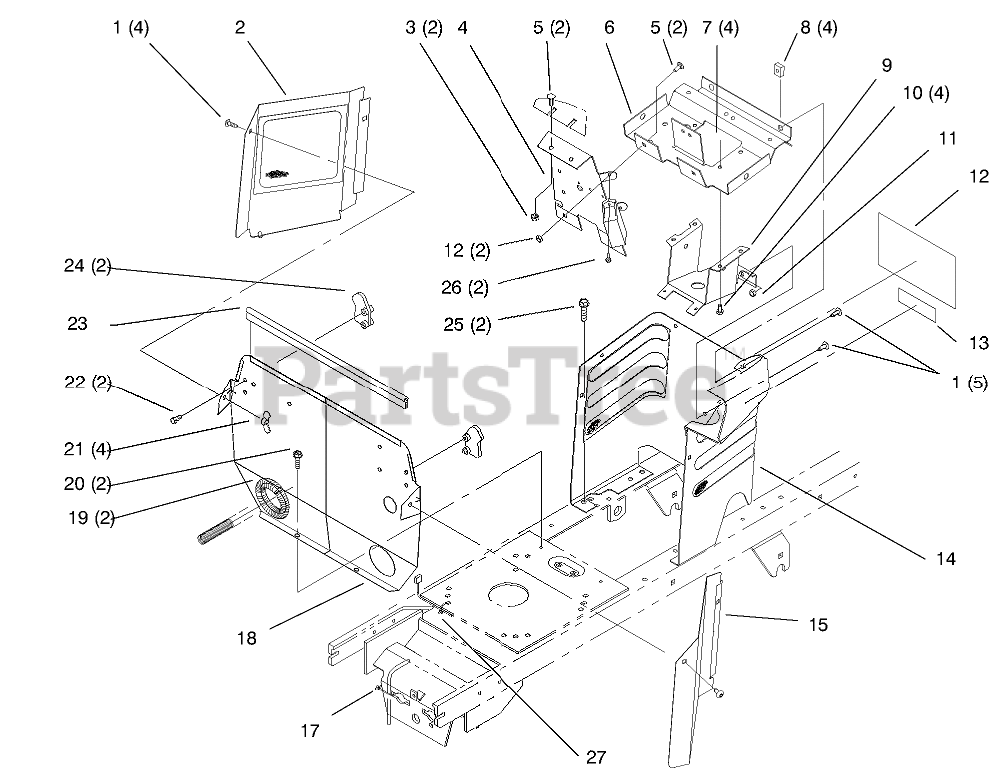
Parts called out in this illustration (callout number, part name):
1	SCREW-HH
2	RH SIDE COVER ASM
3	NUT-KEPS
4	SUPPORT - DASH (BLACK)
5	SCREW-CARR
6	SUPPORT-DASH
7	NUT-HEX
8	NUT RETAINER - J TYPE
9	BRACKET-COLUMN, LOWER
10	SCREW-HH
11	NUT-LOCK, NI
12	DECAL - DANGER
13	DECAL-INSTRUCTION
14	HOODSTAND W/DECALS BLK
15	LH COVER ASM
16	DECAL - 265-6
18	FIREWALL
19	COVER-SHAFT, DRIVE
20	SCREW-HWH
21	NUT-WING
22	SCREW-PLASTITE
23	TRIM-SEAL, FIREWALL
24	LATCH-HOOD
25	SCREW-HWHTF
26	SCREW-PPHTF
